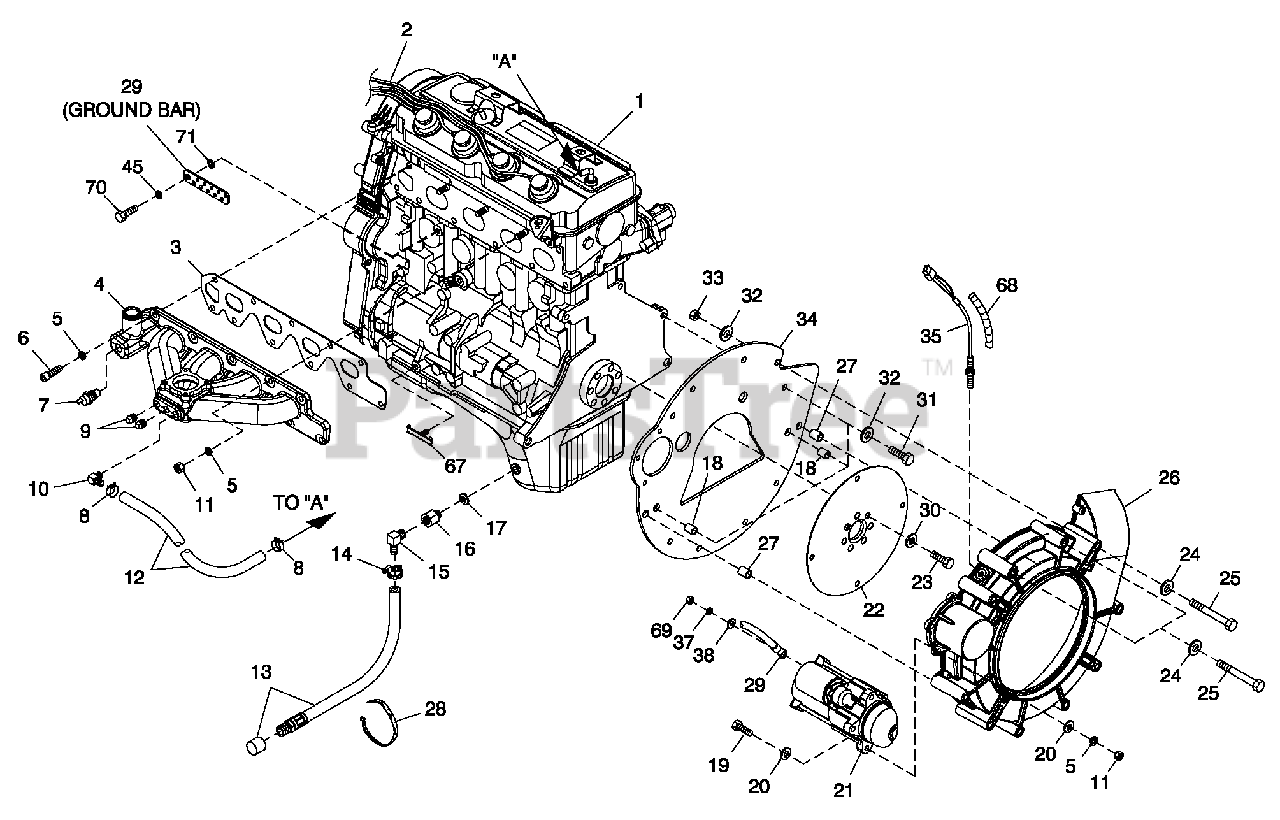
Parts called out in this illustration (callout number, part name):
1	ENGINE 2.4L G2
2	SPARK PLUG WIRE SET 2.4L G2 IG
3	GASKET INTAKE MANIFOLD G2
4	MANIFOLD INTAKE (MACHINED)
5	WASHER LOCK M8-5/16
6	SCREW SHC M8-1.25 X 25 C12.9
7	SWITCH HI-TEMP 245D X 3/8 NPT
8	CLAMP HOSE BAND .63
9	PLUG STD PIPE 1/4 STEEL SQ HD
10	BARBED EL 90 1/4 NPT X 3/8
11	NUT HEX M8-1.25 G8 CLEAR ZINC
12	HOSE 3/8 ID SINGLE BRAID (15" LG)
13	HOSE OIL DRAIN ASSY 16"
14	CLAMP HOSE .38-.87
15	BARBED EL 90 3/8 NPT X 3/8
16	ADAPTER M14-1.50 X 3/8 NPT
17	WASHER NYLON .565
18	BUSHING GUIDE 11.3MM LONG
19	SCREW HHC M8-1.25 X 45 C8.8
20	WASHER FLAT 5/16-M8 ZINC
21	MOTOR STARTER
22	PLATE FLEX 2.4L 10" ALT
23	SCREW HHC M12-1.25 X 15 C10.9
27	BUSHING GUIDE 19.3MM LONG
28	TIE WRAP UL 7.4"X .19" BLK
30	WASHER FLAT .531 ID X 1.062 OD
31	SCREW HHC M10-1.25 X 45 C8.8
32	WASHER LOCK M10 RIBBED ZINC
33	NUT HEX M10-1.25 G8 YEL CHR
34	ADAPTER ENGINE PLATE 2.4L G2
35	ASSY MAGPICKUP(3/8-24 MALE)
36	SCREW HHC M6-1.0 X 12 G8.8
37	WASHER LOCK M6-1/4
38	WASHER FLAT 1/4-M6 ZINC
45	WASHER LOCK M10
67	ANCHOR HARNESS
68	CONDUIT FLEX .25"ID (6"LG)
